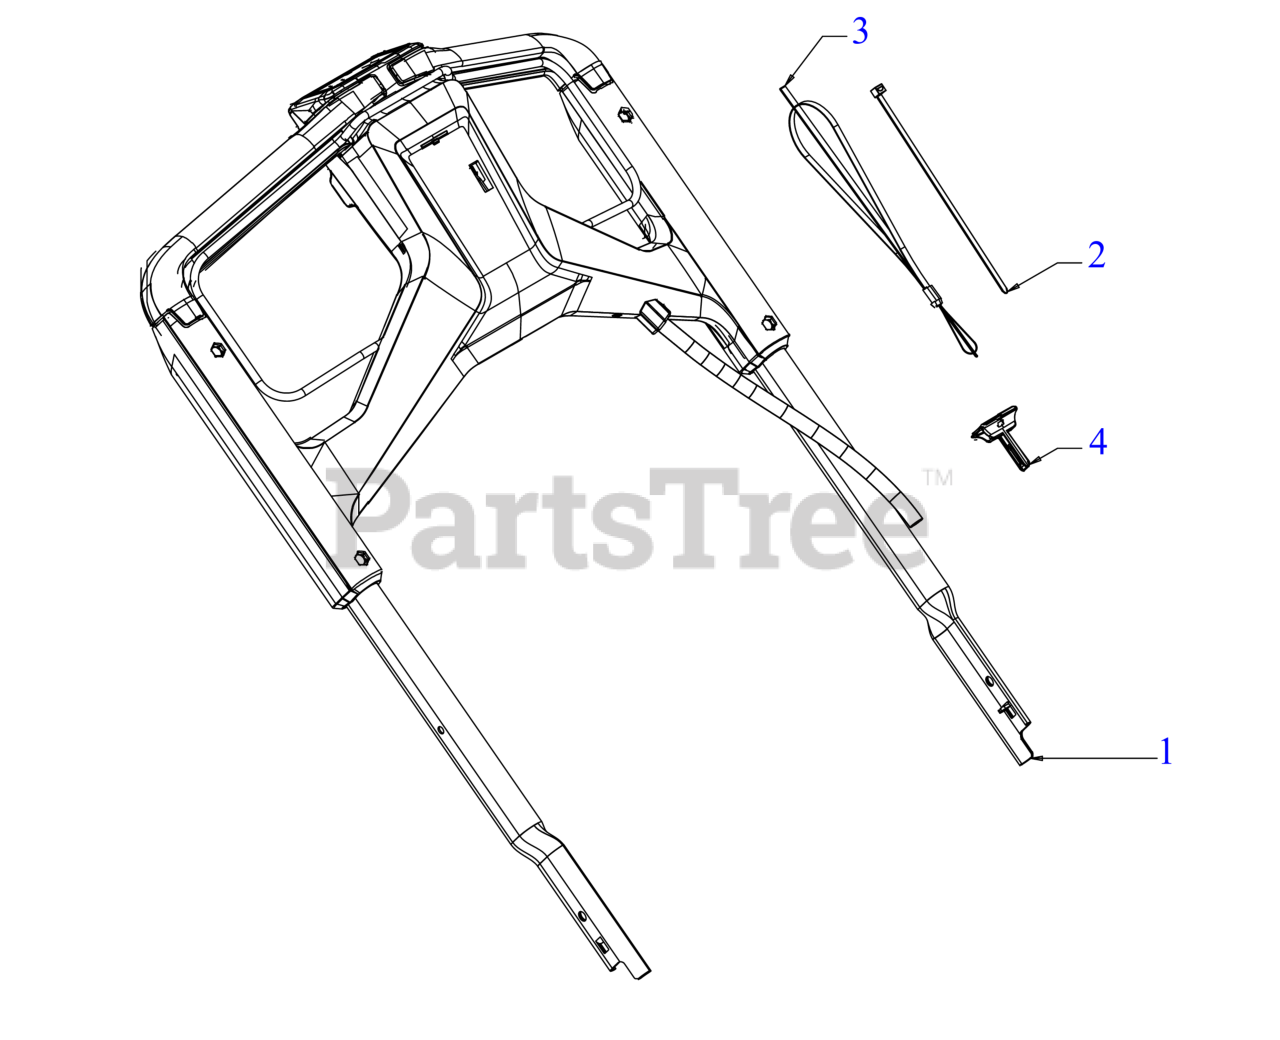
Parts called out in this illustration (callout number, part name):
1	HANDLE PANEL
2	7" CABLE TIE
3	KEY STRAP CORE
4	ELECTRIC KEY
